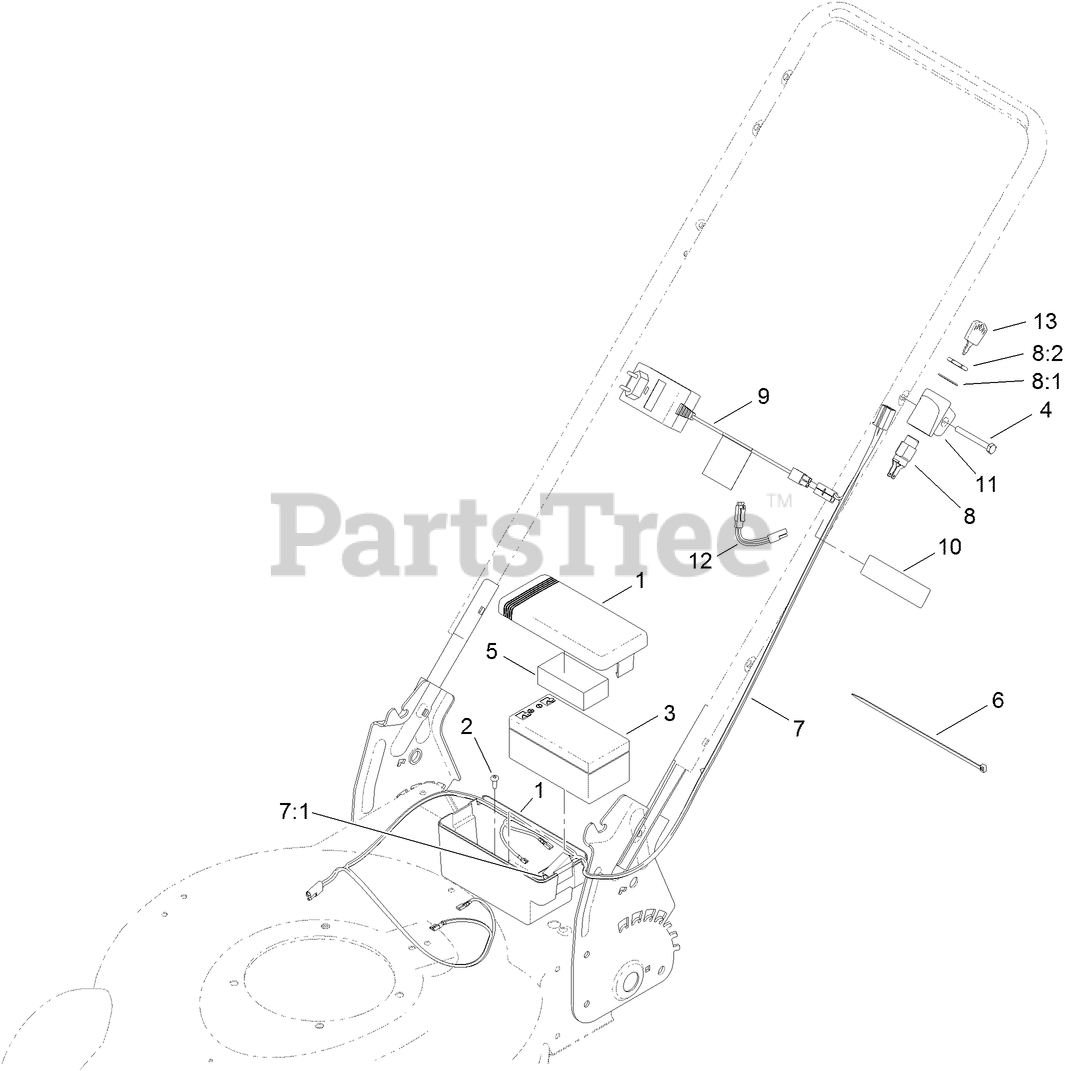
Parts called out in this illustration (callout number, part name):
1	BATTERY BOX ASM
2	SCREW-FORMING, THREAD
3	BATTERY-WET
4	SCREW-HH
5	FOAM-BATTERY, TOP
6	TIE-CABLE
7	HARNESS-WIRE
7:1	FUSE-40 AMP
8	STARTER SWITCH ASM
8:1	WASHER-LOCK
8:2	NUT-HH
9	CHARGER-EUROPEAN, 12V DC
10	DECAL-WARNING
11	MOUNT-SWITCH
12	ADAPTER-CHARGER
